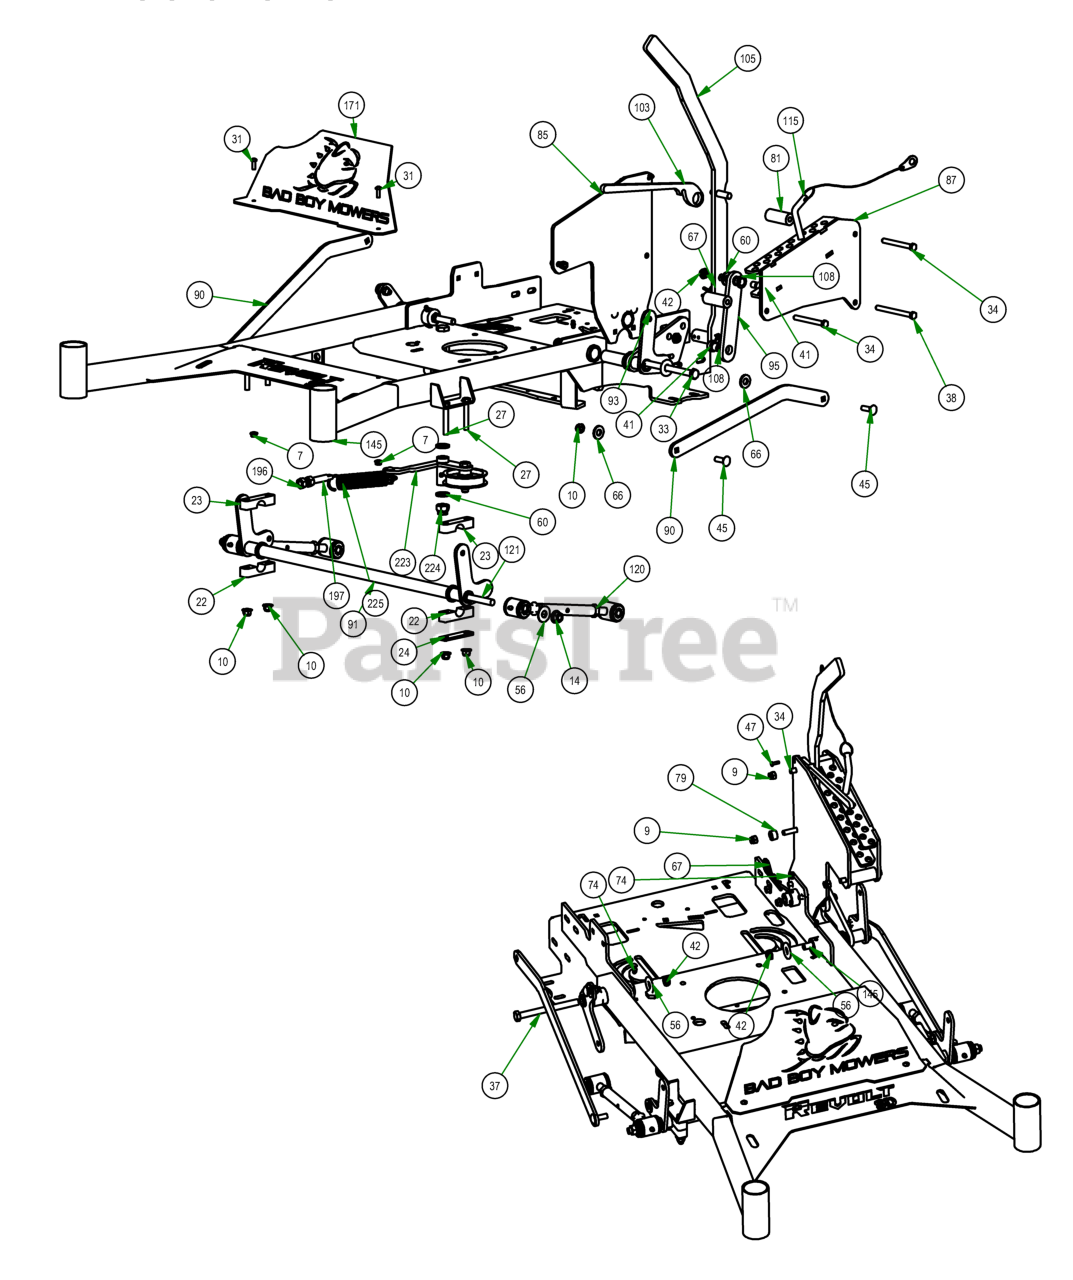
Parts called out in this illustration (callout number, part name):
7	1/4-20 NYL INSERT FLANGE LOCKNUT ZINC
8	10-24 NYLON INSERT LOCKNUT ZINC
9	3/8-16 NYLON INSERT LOCKNUT ZINC
10	3/8-16 Nylon Insert Flange Locknut
13	5/16-18 NYLON INSERT FLANGE LOCKNUT ZINC
14	1/2-13 Nylon Insert Flange Locknut
22	Pillow Block MZ
23	Pillow Block MZ female
24	Pillow Block Strap
27	3/8-16 x 2 1/2" Hex Bolt
31	1/4"-20 x 3/4 Black Oxide 18-8 Stainless Pan Head
33	1/2-13 X 6 HEX CAP SCREW (GR.5) ZINC
34	3/8-16 X 3-1/2 HEX CAP SCREW (GR.5) ZINC
37	1/2-13 X 5 1/2 HEX CAP SCREW (GR.5) ZINC
41	5/8 X 5/8 SOCKET SHOULDER BOLT ZINC YELLOW
42	1/2'' Nylock Nut 1/2 Jam
45	3/8'' x 1 1/4'' Carriage Bolt
47	10-24 X 5/8 BUTTON SOCKET CAP SCREW 18-8 STAINLESS STEEL
53	5/16-18 X 1 CARRIAGE BOLT (GR.8) ZINC
56	1/2 F/W USS 1- 3/8'' OD
60	.635 ID X 1.120 OD X .140 THICK FLAT WASHER NYLON
66	.505 Nylon Spacer
67	Revolt Cotter Pin for 7/8" to 1" shank
74	1/4'' Press in Grease Fitting
79	ACS Spacer 3/4x3/8x1/2
81	Stand On Spacer 2.5''
85	2023 SD Inner Adjustment Plate
86	2023 deck pin plate
87	2023 Stand On Outer Adjustment Plate
90	2023 SD-36 Stand-on Actuator Linkage
91	Revolt Front Actuator Bar Weldment - Raw 2020 36" Black
92	Revolt Rear Actuator Bar Weldment RH 2020 36" Black
93	2023 SD Actuator rear_LH
95	2023 lever secondary linkage
103	2019 Stand On Deck Lever Lock
105	2023 Revolt SD Lift Handle
106	SD Stand on Lever Pivot Actuator Rod
108	.627 ID X .753 OD X .500 LGTH X 1.000 FLG OD X .094 FLG THICK FLANGED BEARING OIL-IMPREG BRNZ
114	Lift Handle Stop Tab
115	2023 stand on Height Adj Pin
120	2018 Maverick Turnbuckle (Top Link)
121	2020 36 Stand On Turnbuckle Rod
145	2023 Stand On Frame Weldment -SD
171	Exhaust Shield SD
196	1/2-13 HEX NUT ZINC
197	All Thread
223	2020 36" Stand-On Drive Belt Pulley Assembly
224	5/8-11 NYLON INSERT LOCKNUT ZINC
225	Deck spring big diameter
